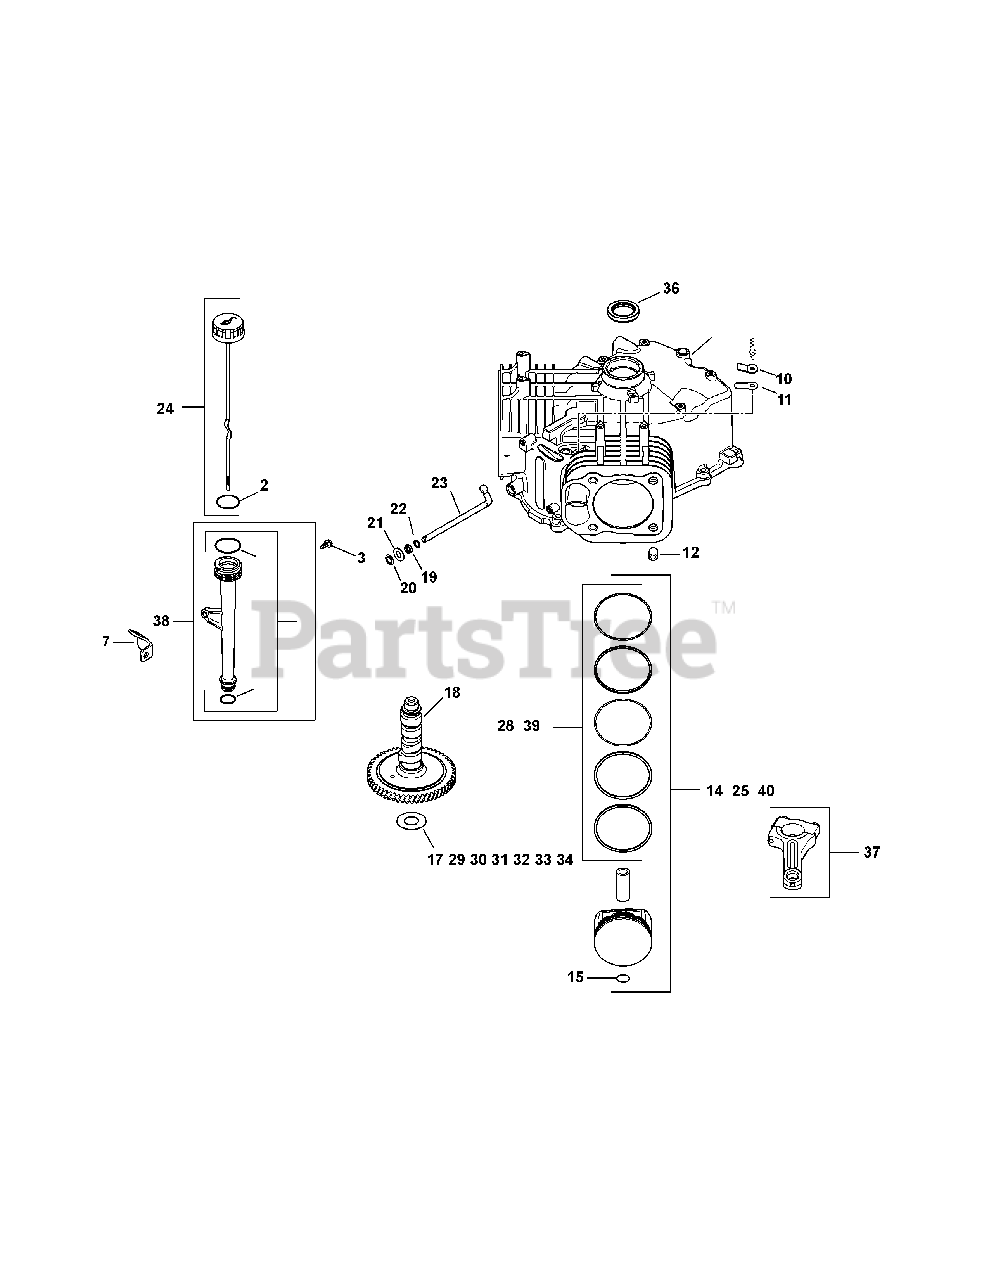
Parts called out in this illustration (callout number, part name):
2	Dipstick Assembly (Cub Yellow)(Inc. 2)
3	Flg. Thd. Frm. Screw, M5 x 0.8 x 13
7	Oil Fill Tube Bracket
10	Breather Reed Retainer
11	Breather Reed
14	Piston Kit w/ Ring Set (Inc. 15 & 16)
15	Piston Pin Retainer
17	Camshaft Shim (White .028")
18	Camshaft Kit (Inc.KH-25-357-14-S)
19	Governor Cross Shaft Seal
20	Ring Retainer
21	Flat Washer, 9mm
22	Flat Washer, 11/32
23	Governor Cross Shaft
24	Dipstick Assembly (Inc. 2)
25	Piston Kit w/ Ring Set (0.25) 83mm
28	Ring Set (.25)
29	Camshaft Shim (Blue .03")
30	Camshaft Shim (Red .032")
31	Camshaft Shim (Yellow .034")
32	Camshaft Shim (Green .036")
33	Camshaft Shim (Gray .038")
34	Camshaft Shim (Black .04")
36	Oil Seal (Helix Lip)
37	Connecting Rod
38	Tube Assembly (Inc. 4-6)
40	Use KH-24-874-27-S Kit
